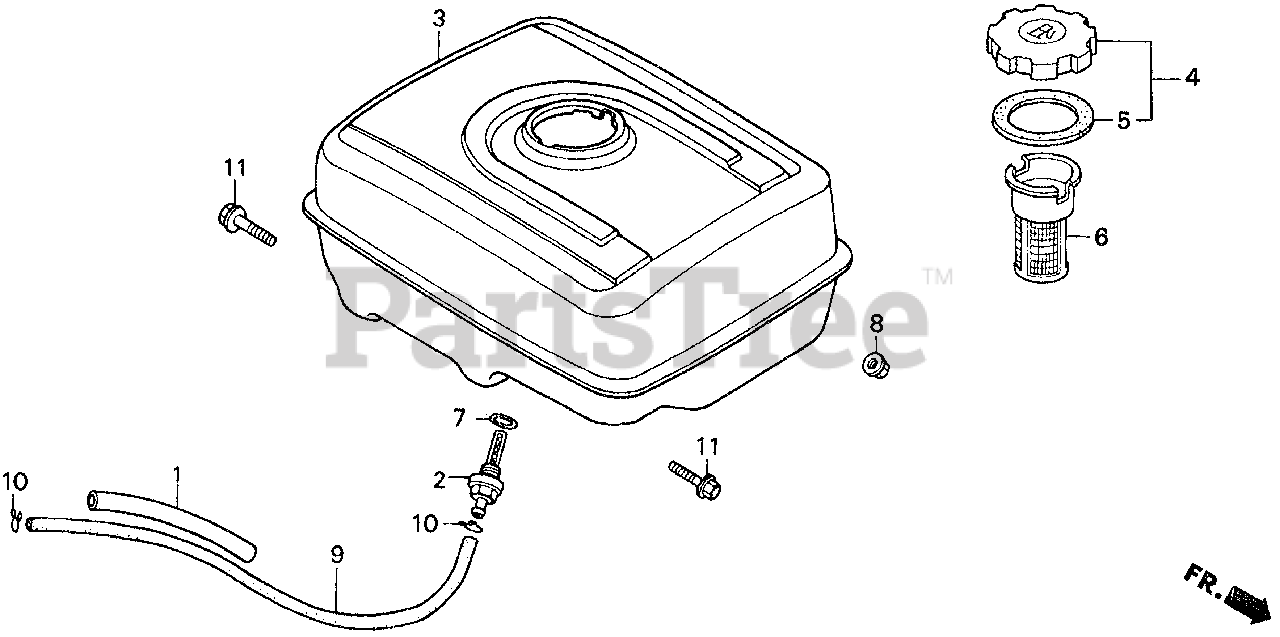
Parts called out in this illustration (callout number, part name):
1	RUBBER, SUPPORTER (107MM)
2	JOINT, FUEL TANK
3	TANK, FUEL *NH31* (MCKINLEY WHITE)
4	CAP, FUEL FILLER
5	GASKET, FUEL FILLER CAP
7	O-RING (13.5X1.5) (ARAI)
8	NUT, FLANGE (8MM)
9	BULK HOSE, FUEL (4.5X3000) (4.5X235)
10	CLIP, TUBE (B8)
11	BOLT, FLANGE (8X25)
